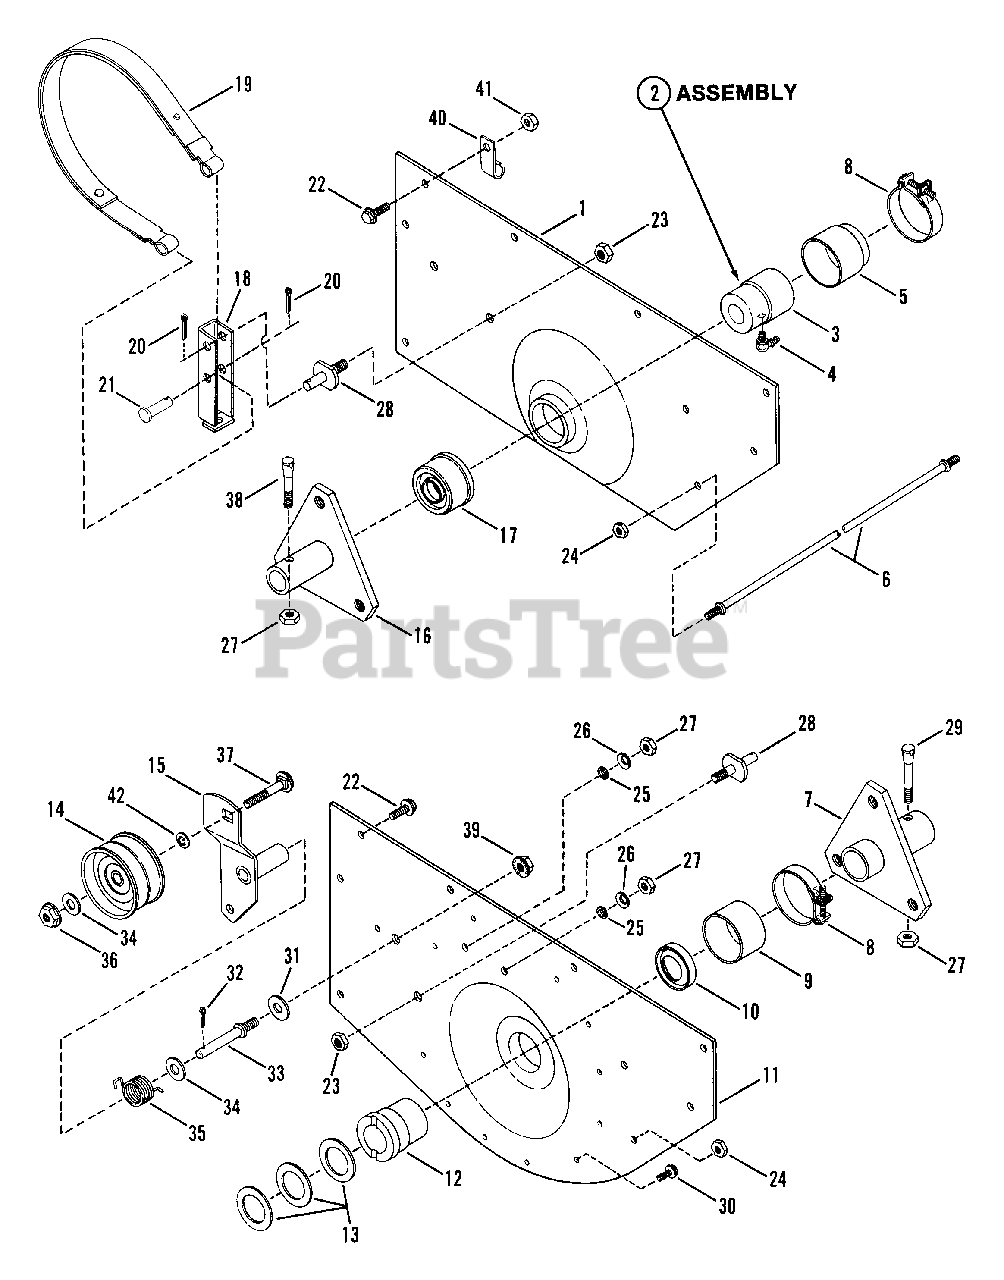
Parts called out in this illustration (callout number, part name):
1	FRAME SIDE, Right Hand
2	ASSEMBLY, Axle Bearing
3	BEARING, Axle
4	FITTING, Lube
5	CAP
6	ROD, Tie
7	HUB, Rear Wheel, Left Hand
8	CLAMP, 1-7/8"
9	CAP, Dust
10	SEAL, 1-1/8"
11	FRAME SIDE, Left Hand
12	BEARING, Axle
13	WASHER, Thrust
14	PULLEY, Idler
15	IDLER ARM
16	HUB, Rear Wheel, Right Hand
17	CAP, Seal L.H. 3/4"
18	ARM, Brake
19	BAND, Brake
20	COTTER-PIN, 1/16 x 1/2"
21	PIN, Clevis
22	SCREW, 5/16-18 x 3/4" Self-Tapping
23	LOCKNUT, 3/8-24 Hex
24	NUT, 5/16-24 Hex
25	O-RING, 5/16"
26	WASHER, Belleville
27	NUT, 5/16-24 Hex Lock, GR C
28	STUD, Brake
29	BOLT, 5/16-24 x 2" Tapered, Left Hand
30	SCREW, 1/4-20 x 1/2" H.W.H. Self-Tapping
31	WASHER, 3/8" Flat
32	COTTER-PIN, 3/32 x 1/2"
33	STUD, Idler
34	WASHER
35	SPRING, Idler Return
36	LOCKNUT, 3/8-16 Hex Flange
37	BOLT, 3/8-16 x 1-1/2" Short Neck Carriage
38	BOLT, 5/16-24 x 1-5/8" Tapered, Right Hand
39	LOCKNUT, 3/8-24 Hex Flange
40	CLIP, Harness
41	NUT, 5/16-18 Hex Center Lock
42	RETAINER, Bolt, 3/8"
